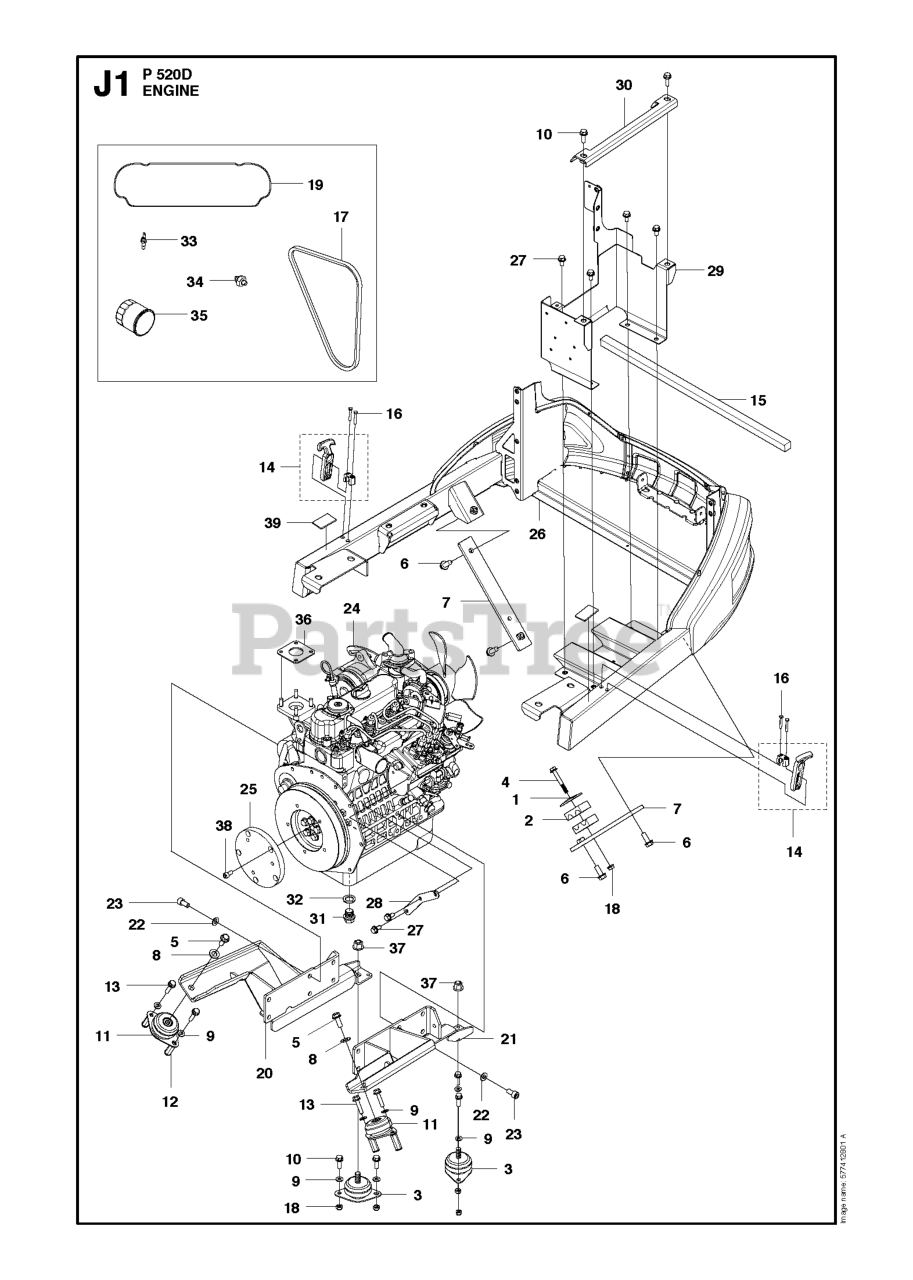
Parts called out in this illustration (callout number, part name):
5	Hex Head Capscrew, M12 X 1.75 X 30 DIN933ZP
8	WASHER - M12
9	WASHER BRB 8.4X17
16	SCREW IHSCM
18	NUT FLANGE
22	WASHER
